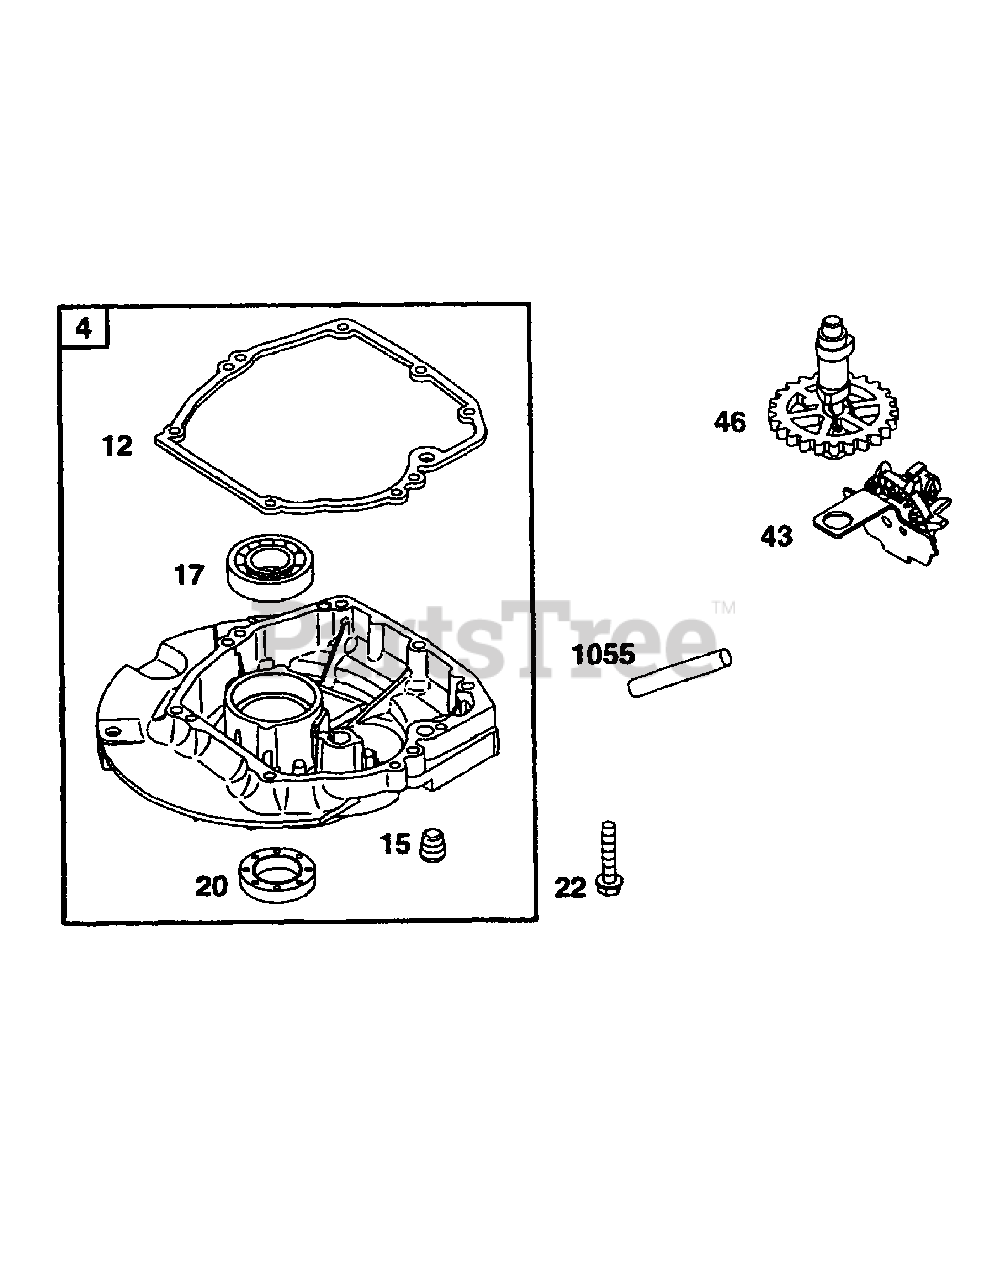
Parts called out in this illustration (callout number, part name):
4	Engine Sump
12	Crankcase Gasket
15	Oil Drain Plug
17	Ball Bearing
20	Oil Seal
22	Screw Hex
43	Governor Oil Slinger
46	Cam Gear
1055	Oil Pump Tube
